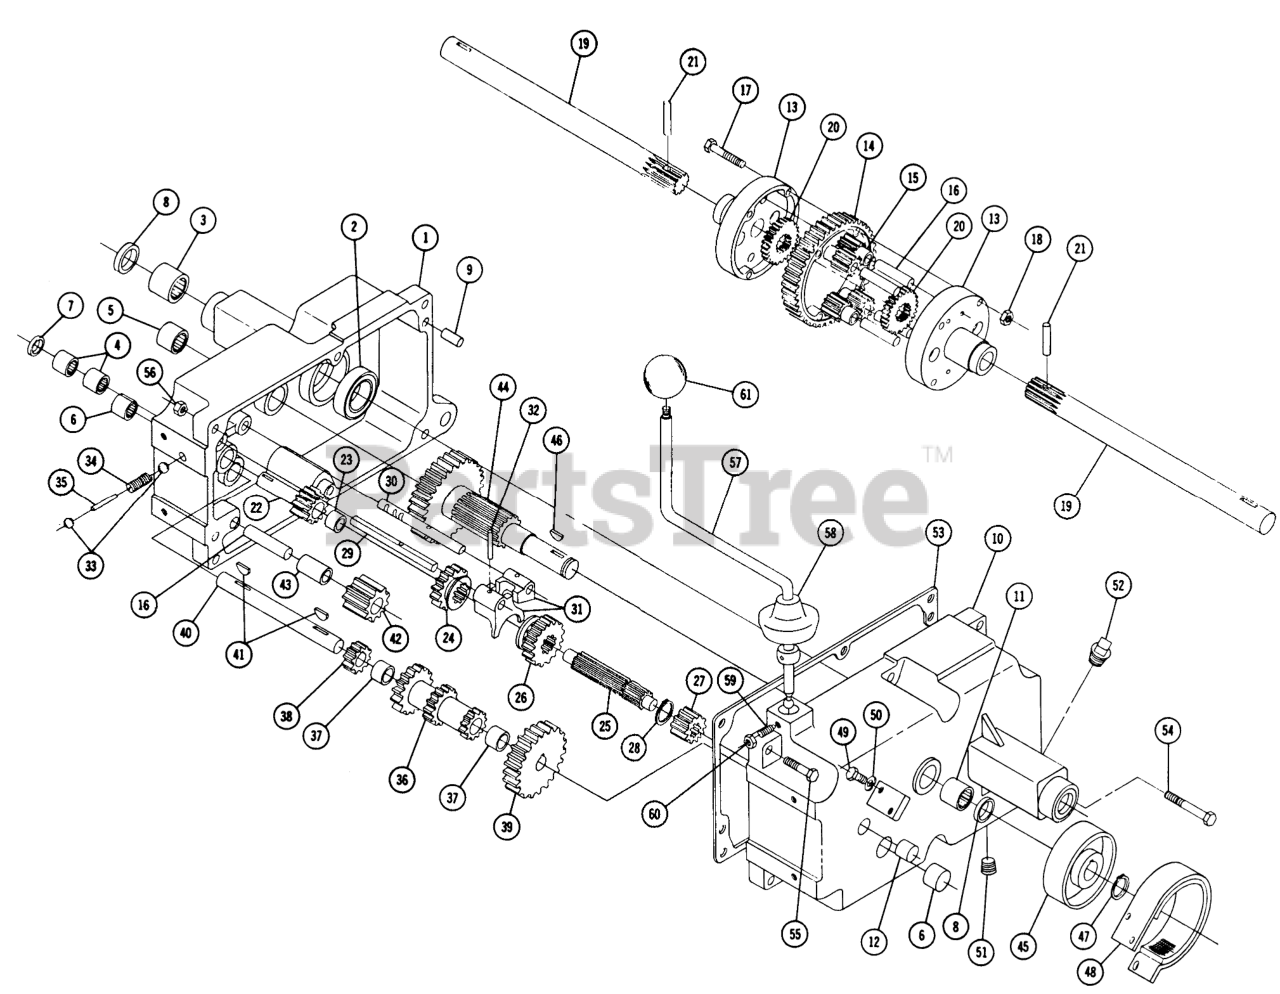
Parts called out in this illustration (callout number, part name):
3	BEARING-NEEDLE
5	BEARING-NEEDLE
6	BEARING-NEEDLE
9	PIN-DOWEL
13	DIFFERENTIAL CASE
14	SVC BULLT 394
16	PIN-DIFFERENTIAL
20	AXLE GEAR
23	BEARING-NEEDLE
27	GEAR
29	RAIL-SHIFT
30	RAIL-REAR SHIFT
31	FORK-SHIFT
32	PIN-ROLL
33	BALL-DETENT
35	PIN-SHIFT
37	BUSHING-BRONZE
39	GEAR-CLUSTER SHAFT
41	Key
42	GEAR/BUSHING ASM-REVERSE IDLER
43	BUSHING
46	KEY-WOODRUFF
49	Bolt-1/4-20 x 5/8
50	Lockwasher
53	GASKET-TRANSMISSION
54	Bolt Hex 3/8-16 x 1
55	Bolt, 3/8 16 x 2
58	COVER-DUST
59	SETSCREW
60	Nut-Nylok
